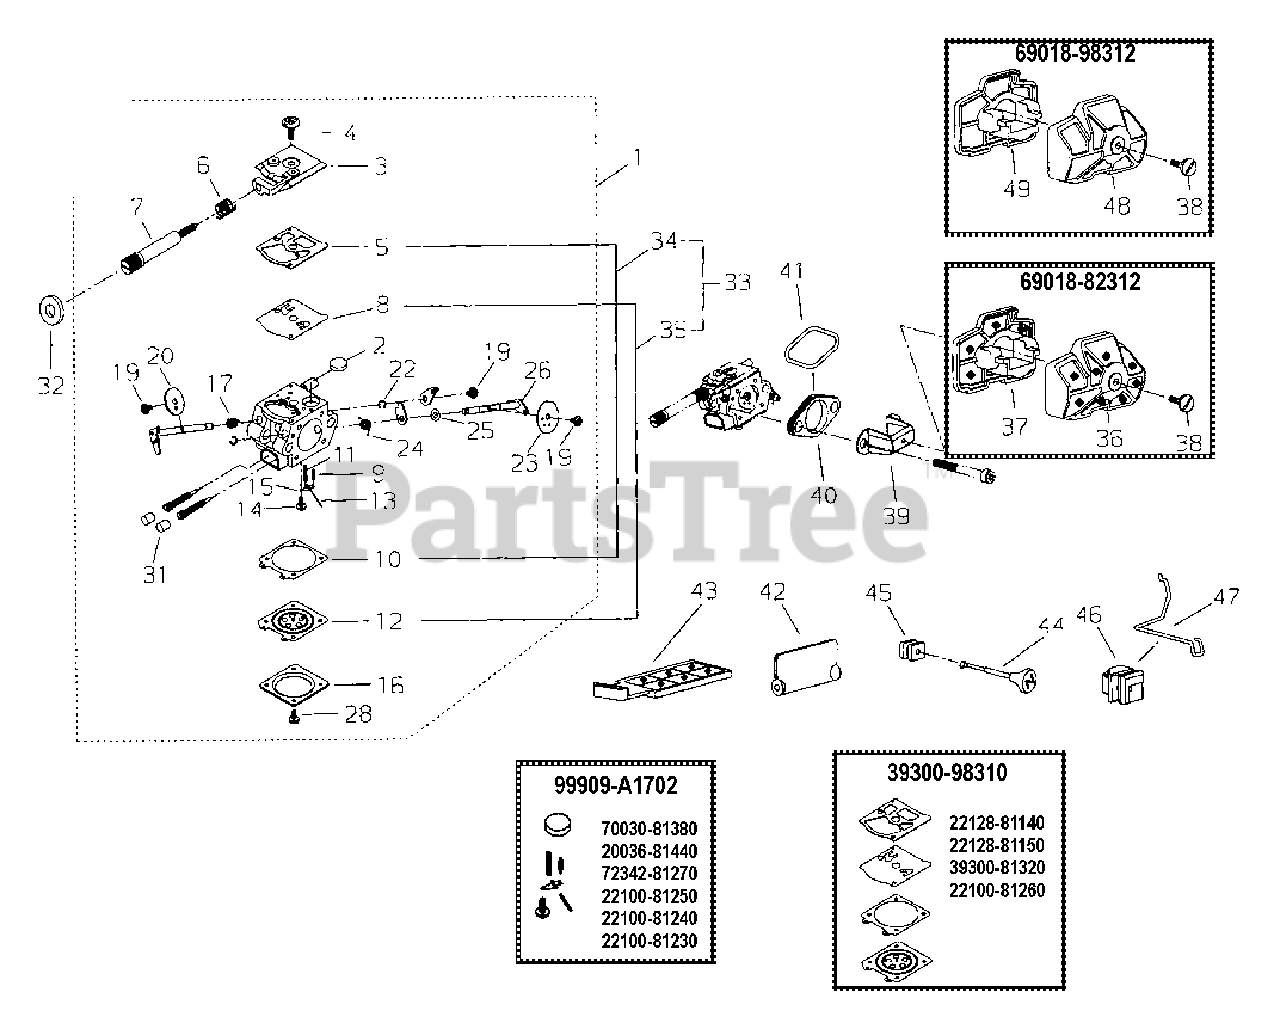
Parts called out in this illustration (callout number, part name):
1	CARBURETOR
2	SCREEN, FUEL INLET
3	COVER ASSY, PUMP
4	SCREW
5	GASKET, PUMP
6	SPRING, IDLE ADJUST
7	SCREW, IDLE ADJUST
8	DIAPHRAGM, PUMP
9	VALVE, INLET NEEDLE
10	GASKET
11	SPRING, METERING LEVER
12	DIAPHRAGM, METERING
13	PIN, METERING LEVER
14	SCREW, METERING LEVER PIN
15	LEVER, METERING
16	COVER, METERING DIAPHRAGM
17	SPRING, THROTTLE RETURN
19	SCREW, THROTTLE STOP
20	VALVE, THROTTLE
22	E-RING
23	VALVE, CHOKE
24	SPRING, CHOKE RETURN
25	WASHER
26	SHAFT ASSY, CHOKE
28	SCREW
31	CAP, LIMITER
32	SEAL, COLLAR
33	DIAPHRAGM/GASKET KIT
34	GASKET KIT
35	DIAPHRAGM KIT
36	COVER, AIR FILTER
37	CASE, AIR FILTER
38	SCREW
39	BRACKET
40	BRACKET
41	O-RING
42	PLATE, SHUTTER
43	PRE FILTER, AIR
44	ROD, CHOKE
45	GROMMET, CHOKE
46	GROMMET, ROD
47	ROD, THROTTLE
48	COVER, AIR FILTER
49	CASE, AIR FILTER
69018-82312	AIR FILTER, MESH
69018-98312	FILTER, AIR - FLOCKED
99909-A1702	REPAIR KIT
